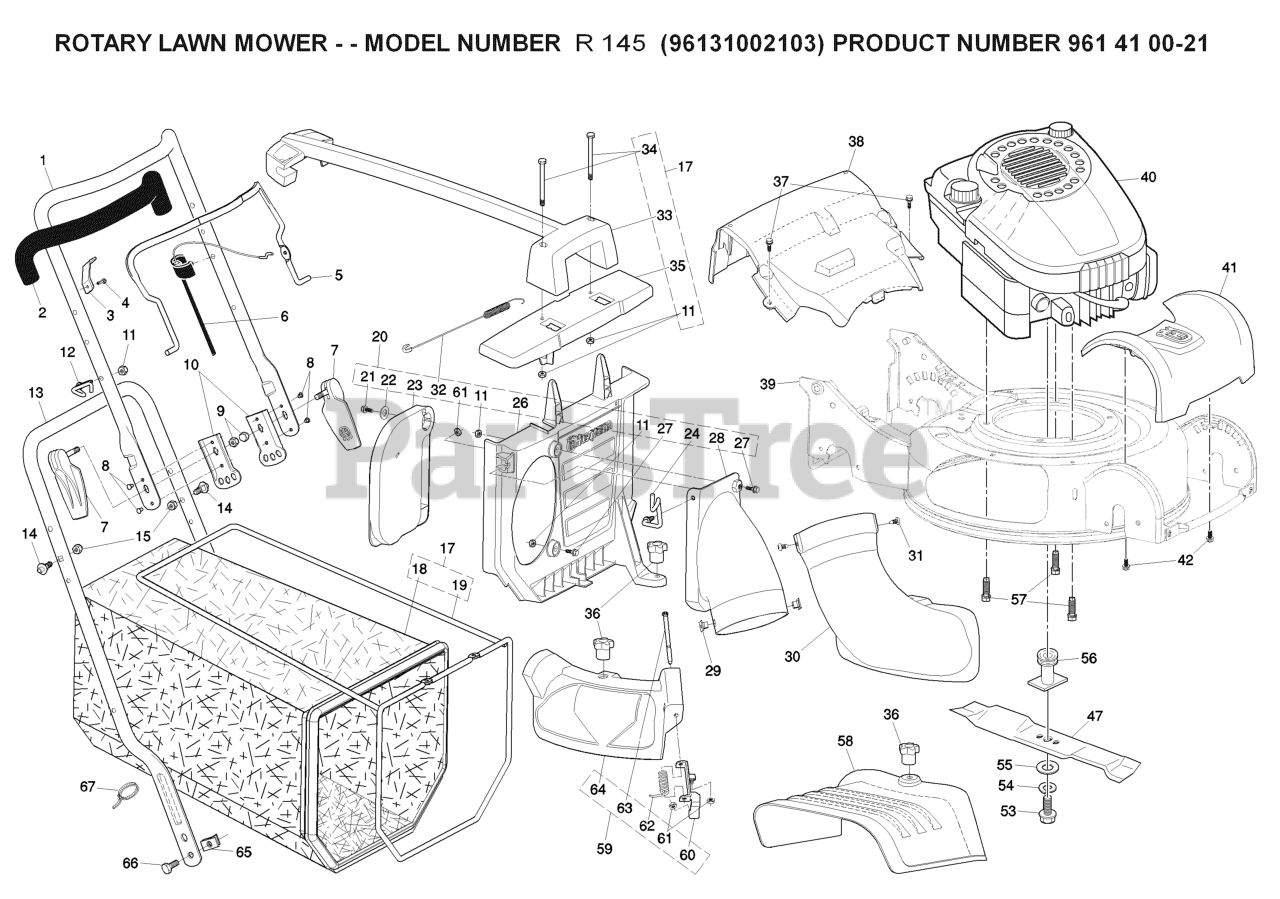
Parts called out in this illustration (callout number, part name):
2	GRIP, FOAM
3	BRACKET
5	BAIL CONTROL
6	CABLE.MZR.50.SNAP-IN
7	ASM.QUICK.RELEASE
9	Locknut, Hex 1/4-20
10	BRACKET.ADJ.3POS.GREY
11	NUT
12	RB GUIDE.ROPE.STD.BLK.ZIN WSL
14	STUD.QUICK.ADJUST
15	NUT.LOCK.5/16-18
22	WASHER
27	BOLT SHOULDER
31	SCREW T-30 1/4-20 X
36	KNOB.MULCH.DOOR
37	SCREW, HEX WASHER HEAD
42	SCREW.HWH.13-16-5.8.BZP
47	BLADE.SWEPT.WING.45CM.H.TREAT
53	BOLT.HD.HEAD.3/8-24X2.50 (2 2)
54	LOCKWASHER
55	WASHER,HARDEN
56	ADAPTER.BLADE.PUSH
57	BOLT 3/8-16X1-1/8
61	NUT.HEX.FLANGE.1/4
62	SPRING.MULCH.DOOR
63	ROD.HINGE.1/4"3.82"
64	DOOR.MULCH.GREY
67	TIE GUIDE
